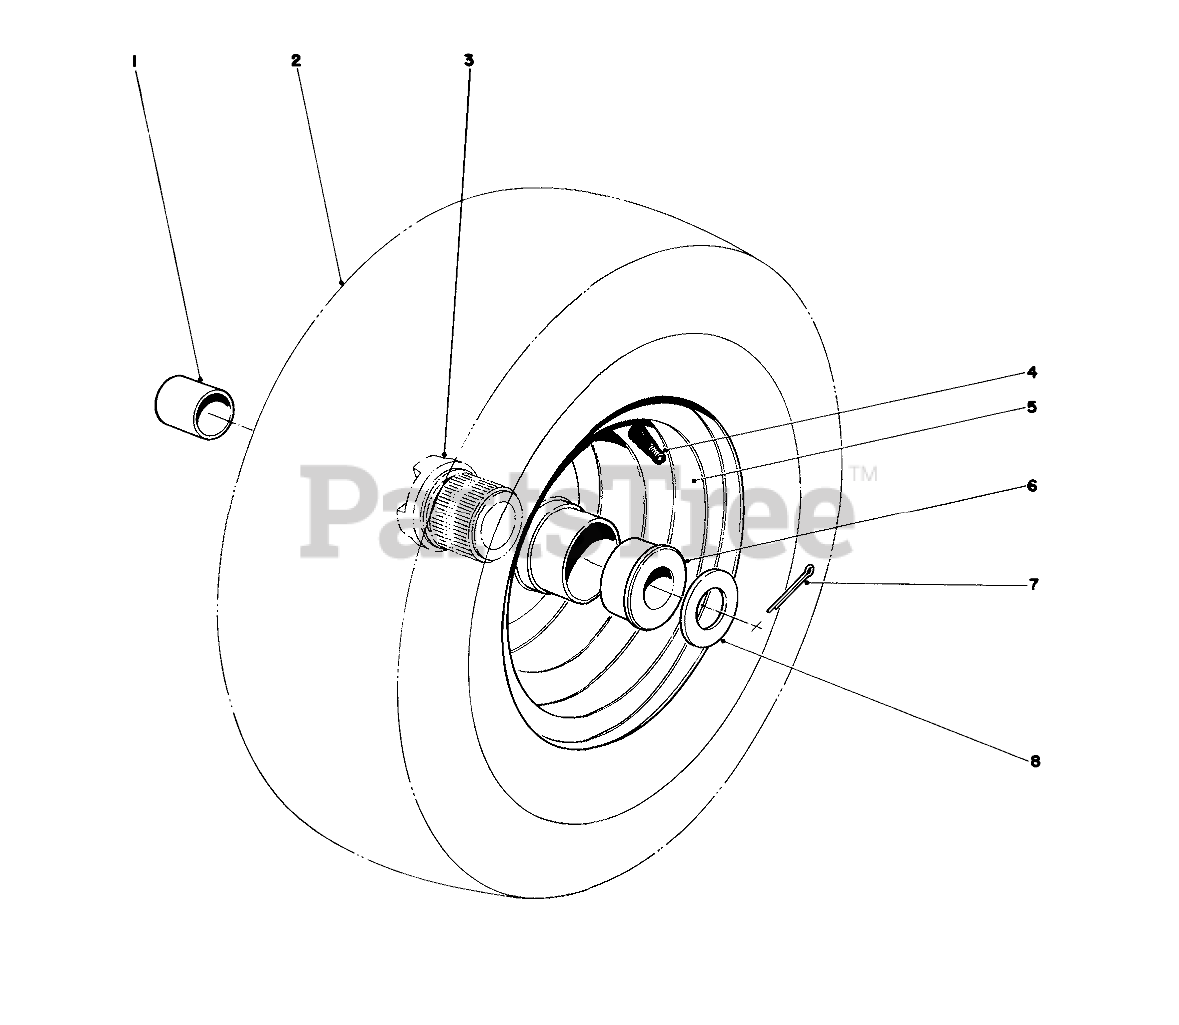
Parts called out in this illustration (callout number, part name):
1	.877ID X .750LG BSHG
3	JAW HUB
4	STEM-VALVE
6	Bushing
7	PIN-COTTER
8	WASHER-THRUST
